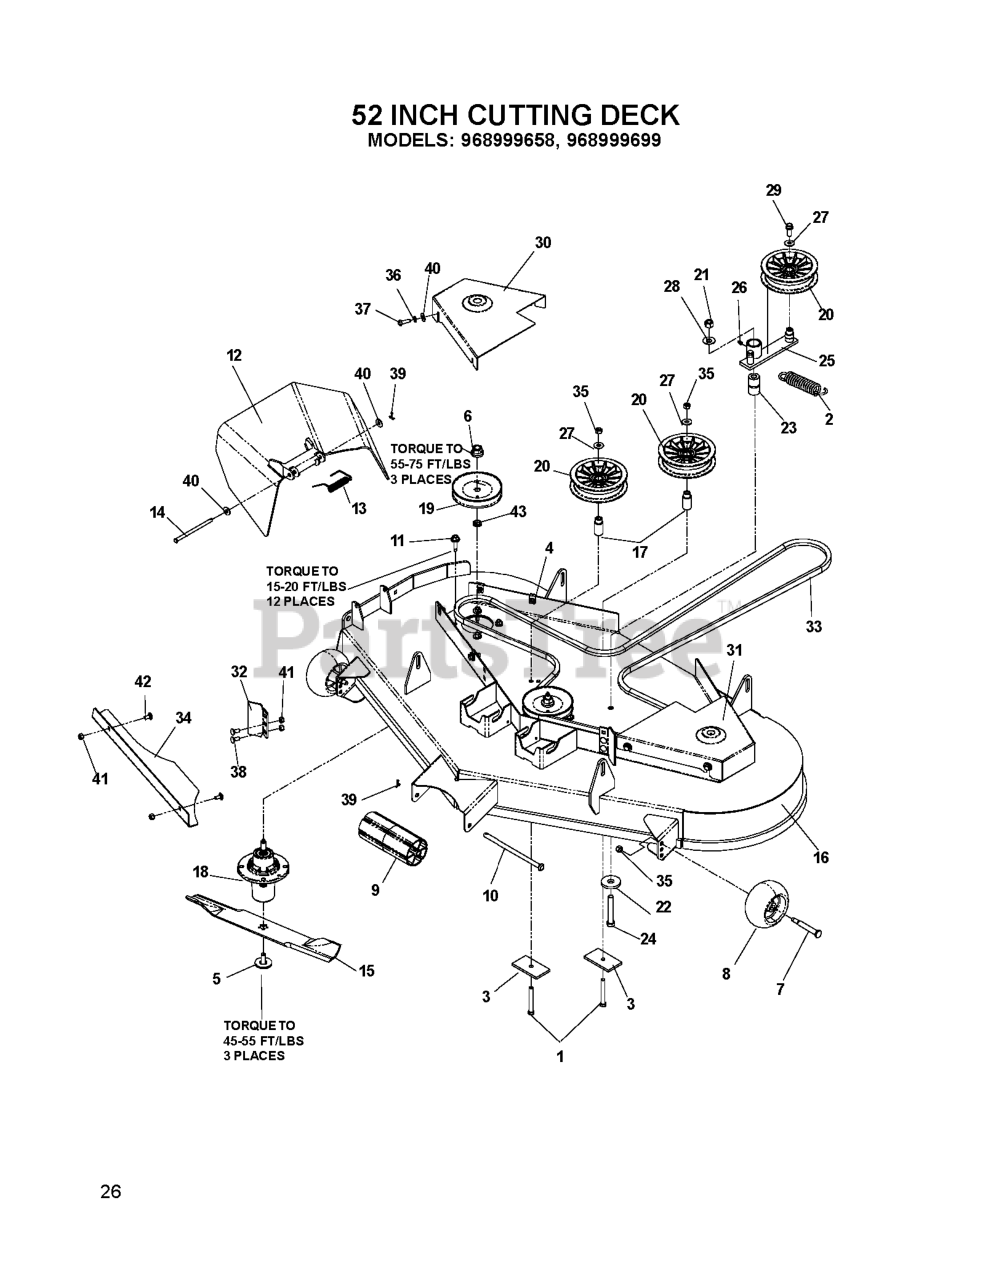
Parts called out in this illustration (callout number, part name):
1	HCS 3/8C X 3
3	SUPPORT PLATE
4	U-CLIP 5/16-18 NUT RETAINER
5	BLADE BOLT ASSY-7/16" TB REPL
6	LOCKNUT - 9/16
7	SHOULDER BOLT 1/2X2-5/8 ZD SPE
8	GAUGE WHEEL
9	NOSE ROLLER-48"
10	NOSE ROLLER ROD
11	WASHER HEAD SCREW
12	DISCHARGE CHUTE 52"
13	SPRING - TORSION
14	PIN-CLEVIS 5/16 DIA X 5.19 ZD
15	BLADE, 18"
16	DECK W/DECALS 52"
17	IDLER BUSHING
18	MANDREL.DECK.ASSEMBLY
19	PULLEY
20	IDLER
21	NUT 1/2-13 HEX NYLOC ZD
22	WASHER, SUPPORT
23	PIVOT BUSHING
24	HCS 1/2C X 3 1/4
26	ZERK
27	WASHER 3/8 FLAT
28	WASHER 1/2 FLAT
29	4CS 3/8C X 1 SERRATED HEAD
30	BELT SHIELD, RIGHT 52, ORG
31	BELT SHIELD, LEFT 52, ORG
33	BELT, DECK 52"
34	CONFINEMENT PLATE, 52"
35	NUT 3/8-16 NYLOC
36	WASHER.LOCK.HVY.HLCL.SPR.5/16
37	HCS 5/16C X 1
38	BOLT 5/16C X 3/4" CARRIAGE
39	RP_COTTER PIN 1/8 X 3/4
40	WASHER 5/16 FLAT
41	NUT 5/16 NYLOC
42	CARRIAGE BOLT 5/16C X 5/8"
43	WASHER-SPACER
